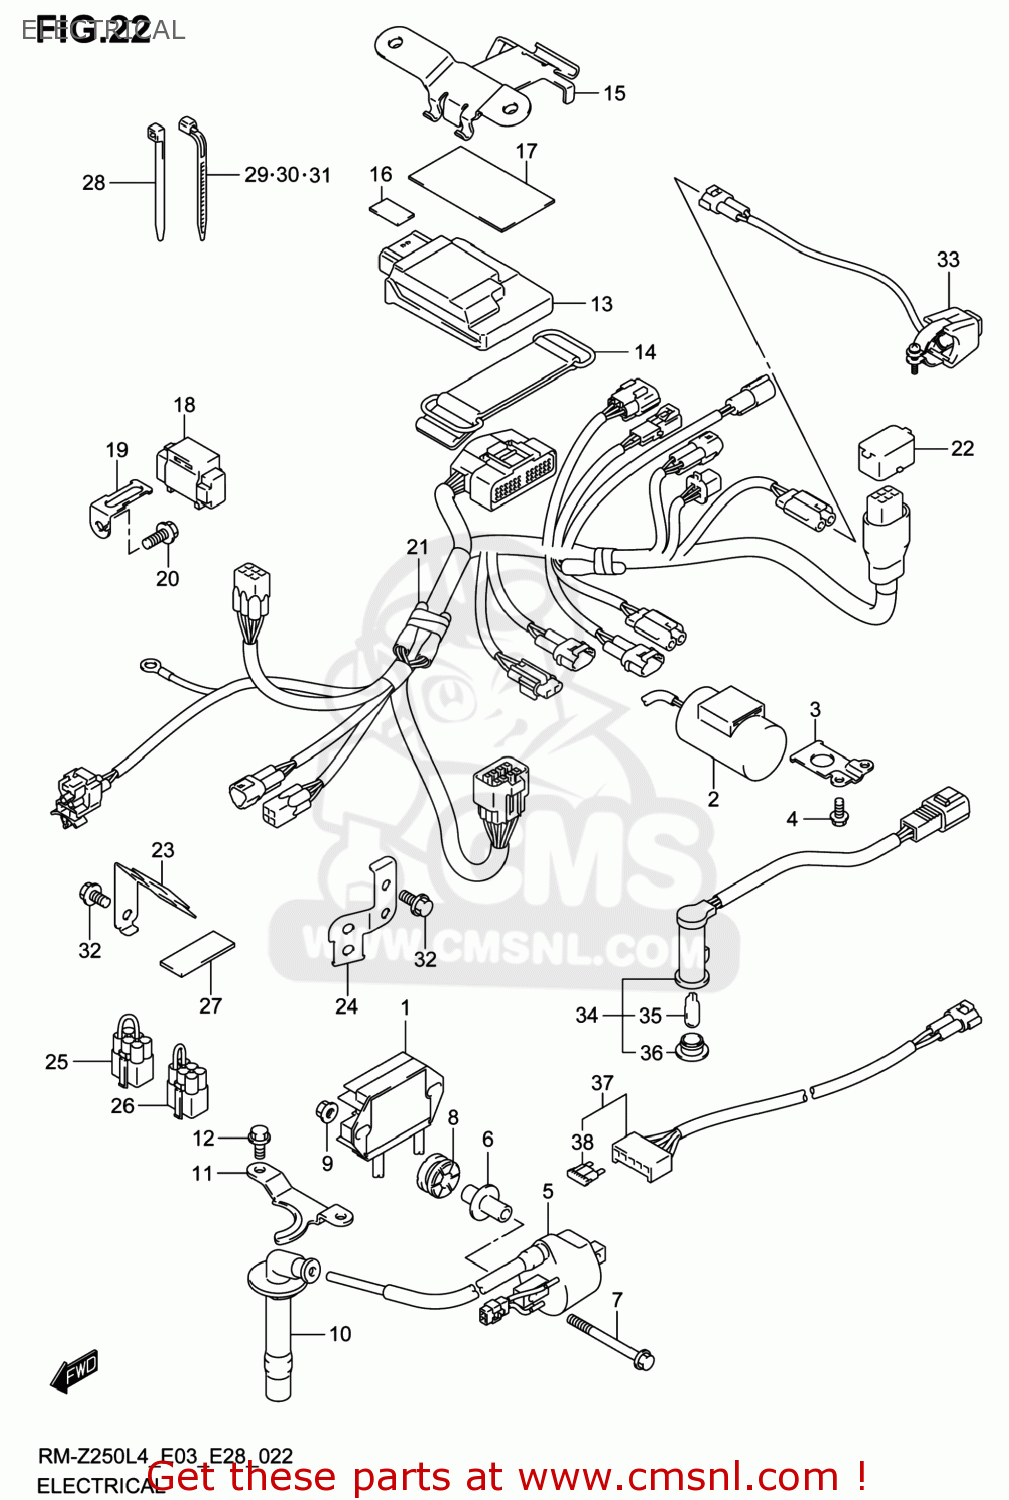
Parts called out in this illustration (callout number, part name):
1	RECTIFIER ASSY
2	CONDENSER ASSY
3	BRACKET,CONDENSER
4	BOLT(6X10)
5	COIL ASSY,IGNITION
6	SPACER,IGNITION COIL
7	BOLT(6X60)
8	CUSHION
9	NUT
10	CAP ASSY,SPARK PLUG
11	RETAINER,IGNITION COIL
12	BOLT
13	CONTROL UNIT,FI
14	BAND,CDI UNIT(L:80)
15	BRACKET,FI CONTROL UNIT
16	CUSHION(30X50X3)
17	CUSHION(30X50X3)
18	SENSOR ASSY,FUEL CUT
19	BRACKET,FUEL CUT SENSOR
20	SCREW
21	HARNESS,WIRING
22	CAP,TS
23	BRACKET,COUPLER
24	BRACKET,COUPLER
25	WIRE,SHORT
26	WIRE,SHORT
27	PROTECTOR,WIRING HARNESS
28	CLAMP(L:95)
29	CLAMP(L:95)
30	CLAMP(L:125)
31	CLAMP(L:165)
32	BOLT
33	SWITCH ASSY,ENGINE STOP
34	LAMP ASSY,FI INDICATOR
35	BULB(12V3.4W,T10)
36	LENS(RED)
37	WIRE,BATTERY
38	FUSE(10A)
